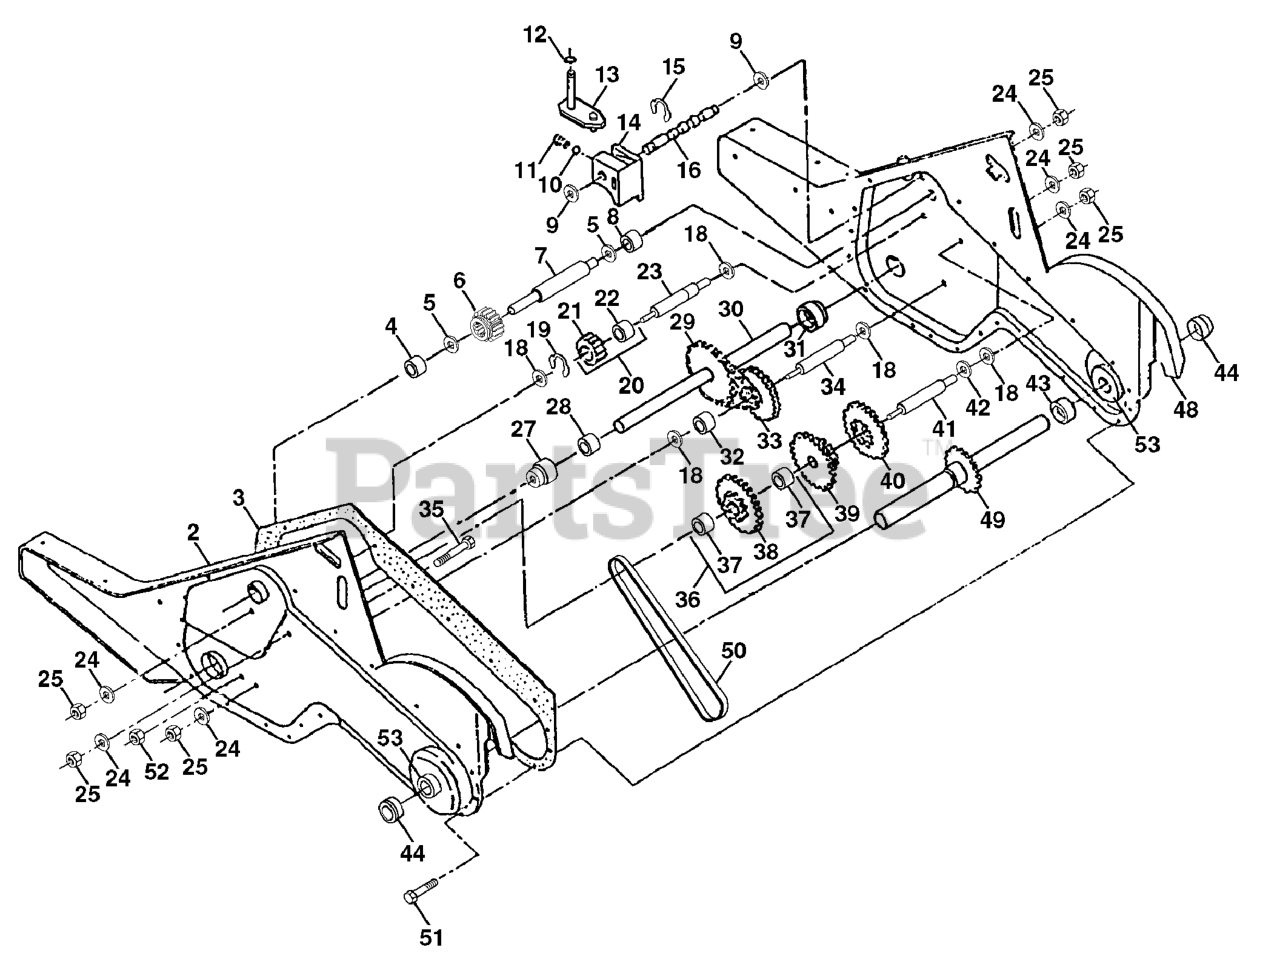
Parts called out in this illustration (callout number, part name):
1	TRANSMISSION ASSY
2	GEARCASE LH W/BRG
3	GASKET TI
4	NEEDLE BRNG LT
5	THRUST WASHER
6	GEAR.PINION.INPUT
7	SHAFT.INPUT."D".TILLER
8	BEARING TI
9	WASHER, SEAL (2 2)
10	STEEL BALL KIT
11	SPRING-SHIFT CRT
13	BRACKET ASM.SHIFT.CRT
14	SHIFT FORK TI
16	SHAFT.SHIFTER.TILLER
20	GEAR ASSY CRT
21	GEAR-REV IDLR CRT
22	NEEDLE BEARING TI
24	LOCKWASHER
25	NUT.ASF.HEX.7/16
27	BEARING, SHAFT LH CRT
30	GROUND SHAFT ASS'Y
31	BEARING, SHAFT RH CRT
33	SPRCKT 8 GEAR CRT
34	SHAFT.SECONDARY.REDUCTION.CRT
35	SCRW WHIZ LOK CRT
36	SPROCKET.ASM.W/BEARING.TILLER
37	BEARING
38	SPROCKET, TINE
41	SHAFT.REDUCTION.TILLER
42	BRNG RACE T
44	SEAL ASM, OIL
48	GEARCASE RH W/BRG
49	TINE SHAFT
50	CHAIN.TILLER
51	SCREW
52	NUT
53	BEARING KIT
